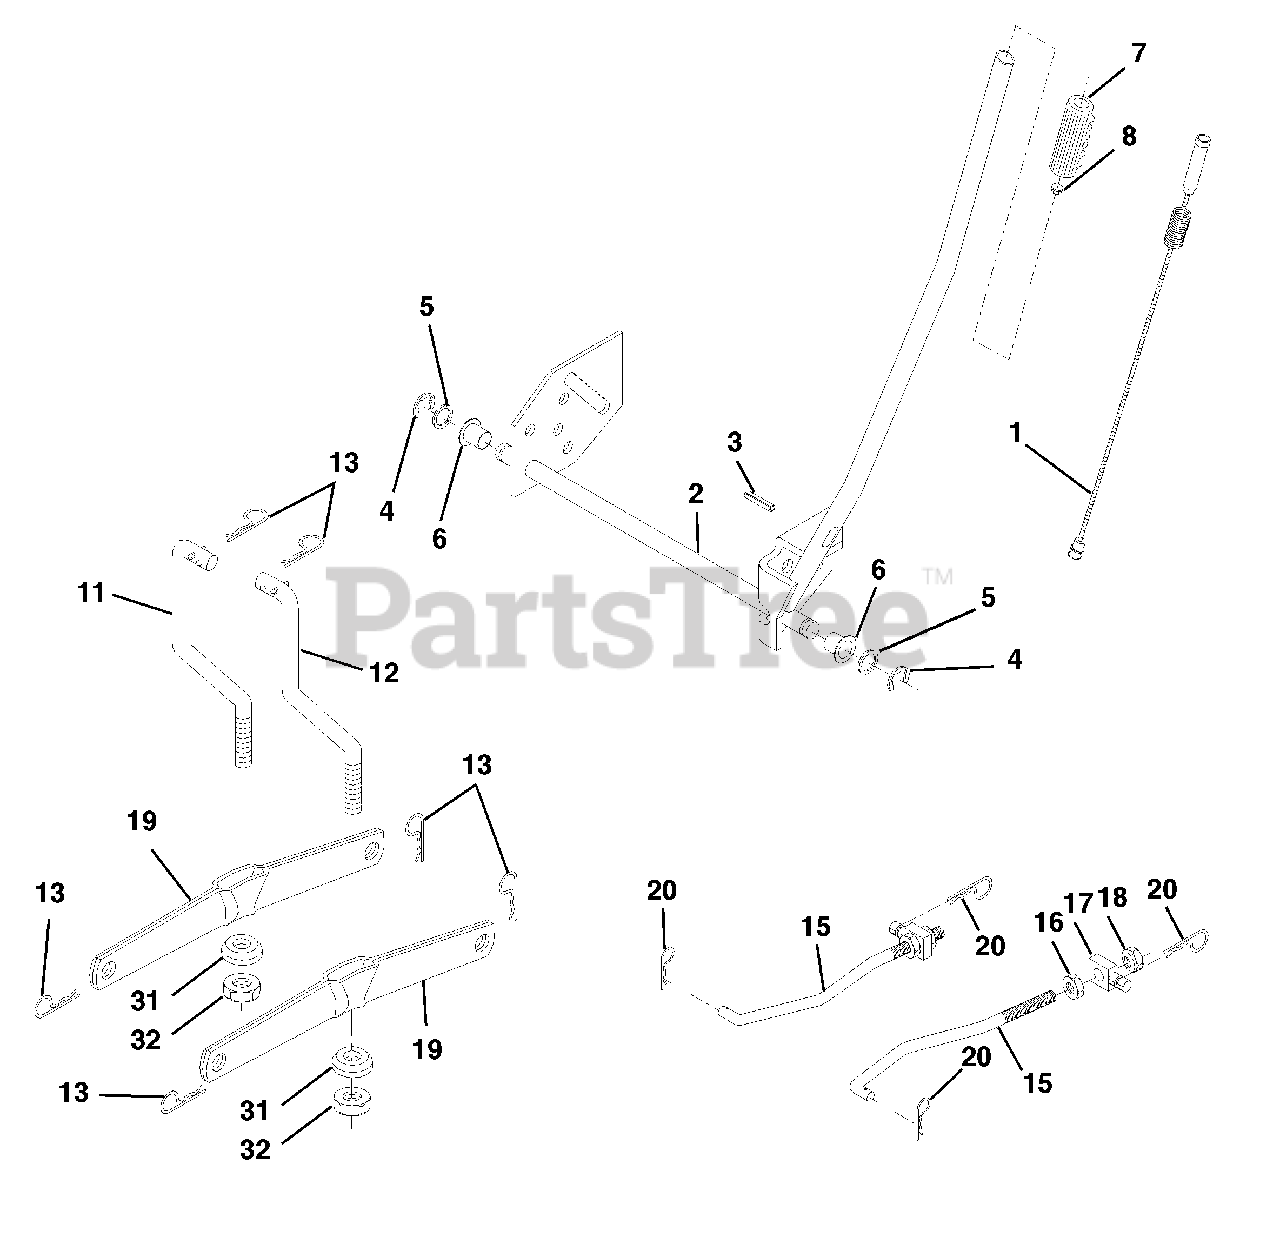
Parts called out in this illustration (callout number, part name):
1	Wire Asm Inner/Spring W/plunger
2	Shaft Asm Lift
3	Pin Groove
4	E Ring #5133-62
5	Washer PLTD 21/32 x 1 x 21ga
6	Bearing Nylon Blk 629 Id
7	Grip Handle Bicycle
8	Button Plunger Black
11	Link Lift LH
12	Link Lift RH
13	Retainer Spring
15	Link Front
16	Nut Jam Hex 1/2-13 Unc
17	Trunnion Blk Zinc
18	Nut Lock W/wsh 1/2-13unc
19	Arm Suspension Rear
20	Spring, Retainer
31	Bearing Pvt. Lift Spherical
32	Nut Crownlock 3/8-24
